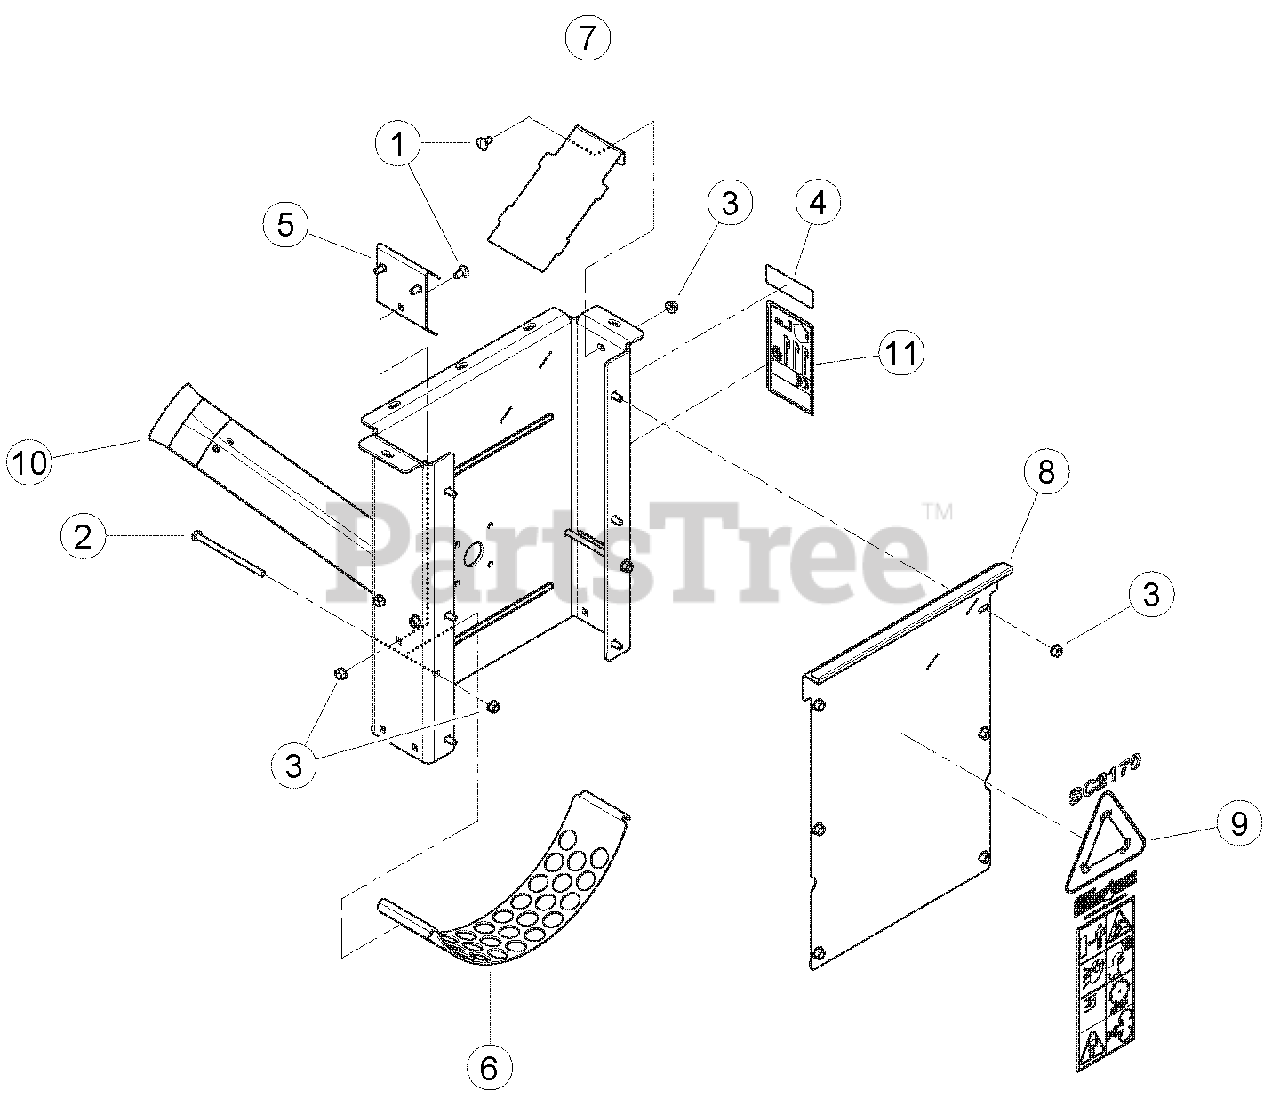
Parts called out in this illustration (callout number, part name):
1	BOLT, 5/16 X 5/8 CRG GR5 ZP
2	BOLT, 5/16 X 5 HEX HD NC GR5 ZP
3	NUT, 5/16 SPIRAL LOCK
4	DECAL, SERIAL NUMBER
5	PLATE, DEFLECTOR
6	SCREEN, SC2170 SMALL COARSE
7	PLATE, RESTRICTOR
8	ASSEMBLY, SC2170 PANEL SERVICE
9	DECAL, SC2170 INFORMATION
10	ASSEMBLY, SC2170 CHUTE SERVICE
11	DECAL, SC2170 CE INFORMATION
